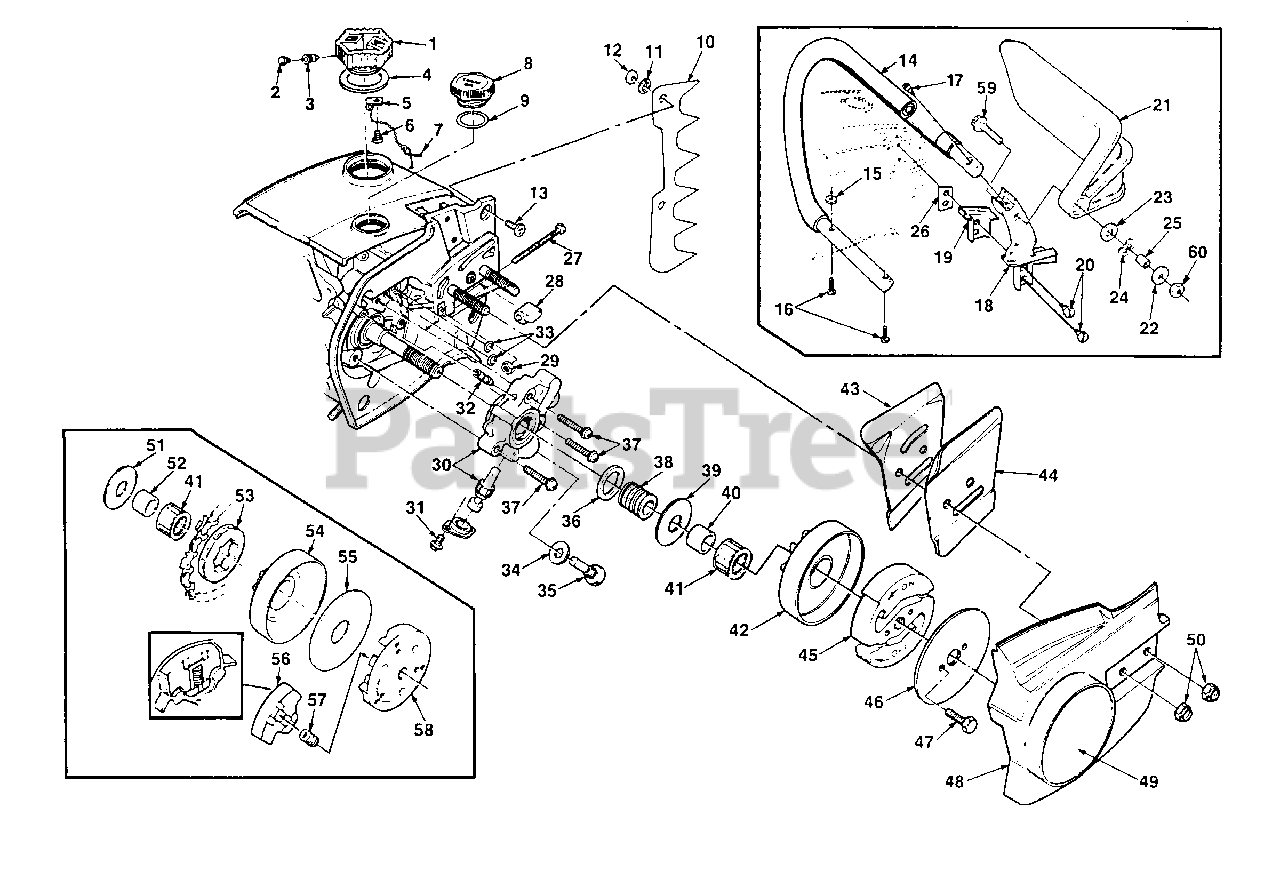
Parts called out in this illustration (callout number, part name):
1	CAP- Fuel filler
2	FILTER- Filler cap
3	VALVE- Check
4	GASKET- Fuel filler cap
5	CHAIN- Bead
6	SCREW- Pan hd., plastite 6 x 1/4
7	RETAINER- Filler cap
8	CAP- Oil filler (Vented)
9	GASKET- Oil cap
10	KIT- Spiked bumper (accessory)
11	WASHER- Lock #10
12	NUT- Hex 10-32
13	SCREW- Flat 10-32 x 5/8
14	HANDLE BAR- Flush cut
16	SCREW- 10-32 x 7/8
17	SCREW- Soc., 10-32 x 7/8
18	KIT- Handle bar bracket (flush cut)
19	MOUNT- Shock
20	SCREW- Shoulder
21	HAND GUARD
23	WASHER- Belleville
24	WASHER- Spring
26	PLATE- Handle bar bracket
27	SCREW- Guide bar adjusting
28	PIN- Bar adjusting
29	NUT- Lock, 10-32
30	PUMP- Automatic oil
31	SCREW- Pan 4-40 x 1/4
32	FITTING- Tube
33	"O" RING
34	GASKET- Cam screw
35	SCREW-Cam
36	SEAL- Oil pump
37	SCREW- Pan 8-32 x 3/4
38	GEAR- Worm
39	WASHER- Thrust (Outer)
40	RACE- Inner
41	BEARING- Needle
42	SPROCKET & DRUM (std.)
43	PLATE- Guide bar (Inner)
44	PLATE- Guide bar (Outer)
45	CLUTCH
46	PLATE- Clutch
47	SCREW- Hex hd. 10-32 x 1/2
48	COVER- Drivecase
49	DECAL- Drivecase cover
50	NUT- Hex, 5/16-18
51	WASHER- Thrust (Outer)
52	RACE- Inner
53	SPROCKET- Rim type, 3/8 .7 tooth
54	HUB & DRUM
55	WASHER- THRUST (Inner)
56	SHOE- Clutch
57	SPRING- Clutch
58	PLATE- Clutch (aluminum)
59	SCREW- Flat hd. 12-24 x 1
60	NUT- Hex 12-24
